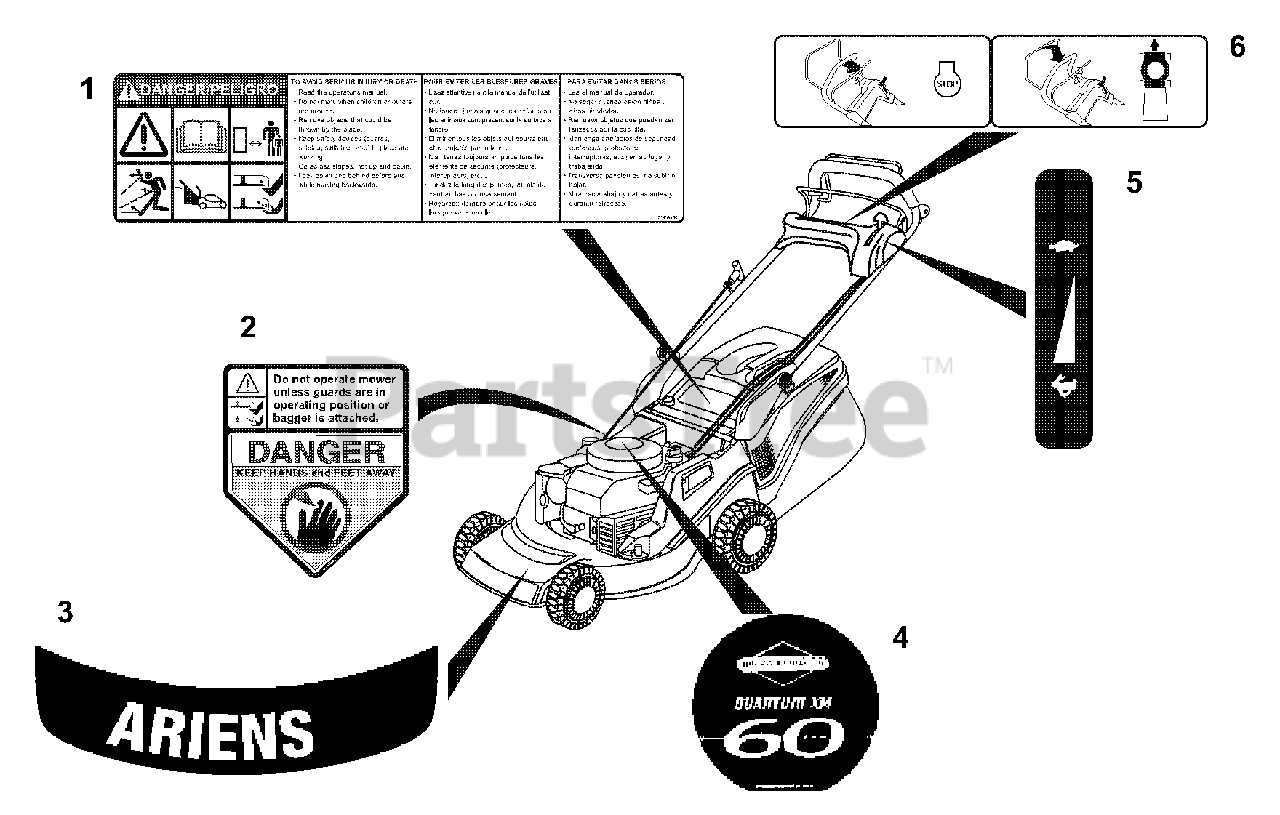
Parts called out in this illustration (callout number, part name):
1	DECAL, DANGER
2	DECAL, CPSC DANGER
3	DECAL, ARIENS 21" DECK
4	DECAL, ENGINE B&S QUANTUM 6.0
4	DECAL, HONDA GCV 160 ENGINE
5	DECAL, THROTTLE
5	DECAL, THROTTLE AND SPEED
6	DECAL, CONTROL PUSH
6	DECAL, CONTROL SELF-PROP
